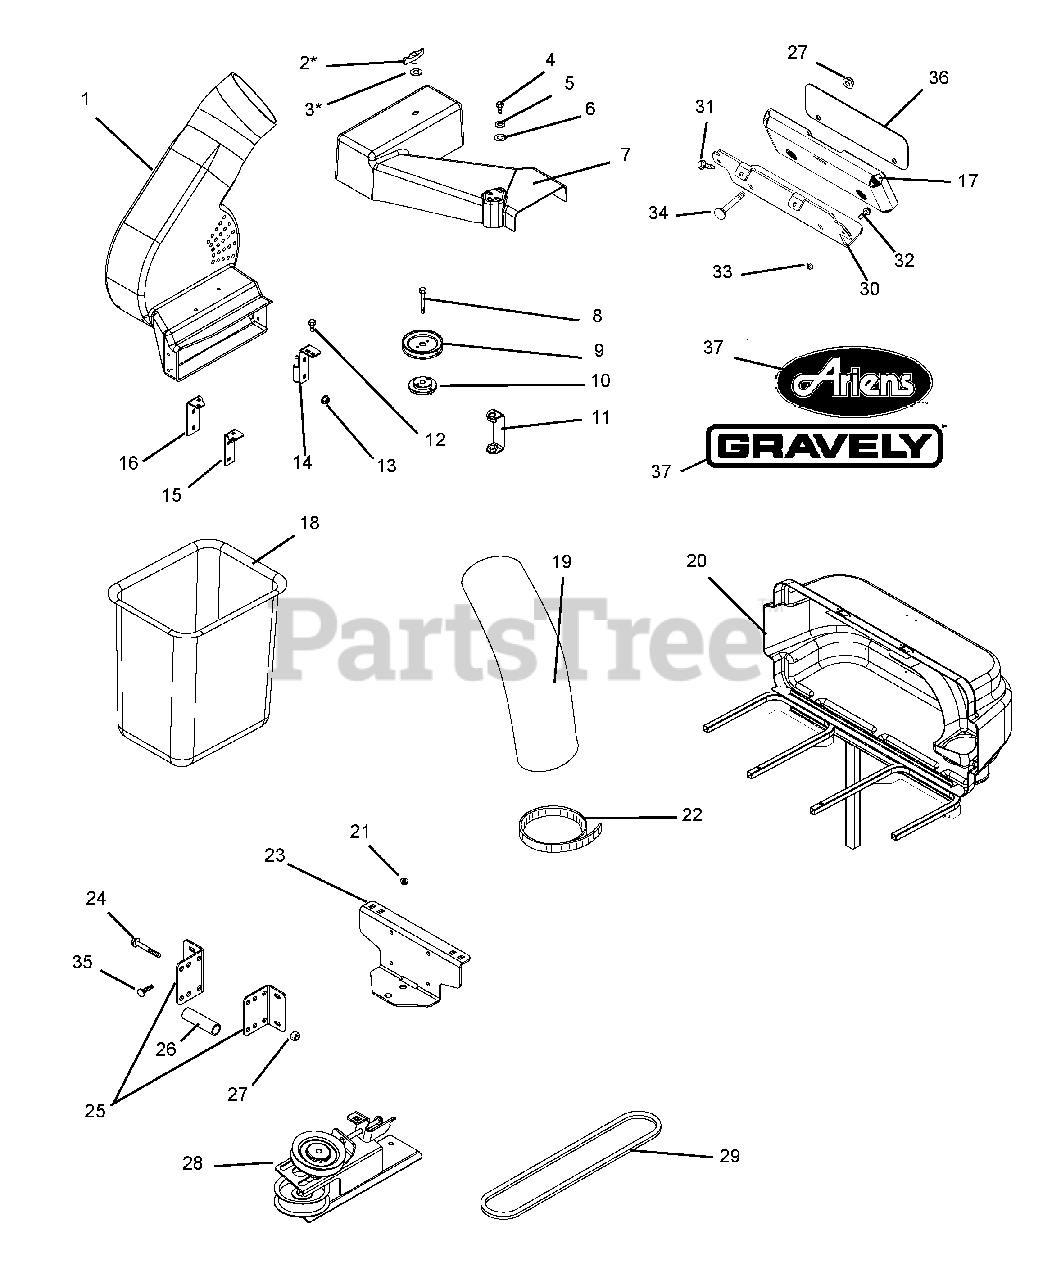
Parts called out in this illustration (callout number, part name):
1	BLOWER (SERVICE ASSEMBLY)
2	KNOB - WING .312-18 UNC
3	WSHR-FL-STL .380X1.50X.062 YWZ
4	@BLT-HEX .38-16X.75 GR5 YWZC
5	@WSHR-LK .38X.094 REG YWZC
6	@WSHR-FL-STL.438X1.00X.083 YWZ
8	BLT-HEX .38-16X1.75 GR8 M-EPYZ
9	SHEAVE, 3.00 DIA.
9	SHEAVE, 4.00 DIA.
10	ASSEMBLY, SHEAVE ADAPTER
11	SPACER, COVER
12	@BLT-HEX .25-20X.75 GR5 YWZC
13	@NUT-LK-TOP-FLG .25-20 YWZC
14	WELDMENT, REAR MOUNT BRACKET
15	BRACKET, FRONT
16	WELDMENT, FRONT MOUNT BRACKET
17	WEIGHT, CAST IRON
18	GRASS BAGGER BASKET
19	HOSE, FLEXIBLE-47"
20	Cover Assembly
21	@NUT-LK-TOP-FLG .38-16 YWZC
22	CLAMP, 7" TOOL-LESS HOSE
23	ASSM, TRAILER HITCH
24	@BLT-HEX .50-13X3.00 GR5 YWZC
25	BKT,BAGGER MOUNT
26	SPACER, PIVOT .500X.750X1.805
27	@NUT-LK-TOP-FLG .50-13 YWZC
28	Idler Assembly
29	V-BELT, HA-WRAPPED
29	V-BELT, HA-RAW EDGE
30	BKRT, CZ WEIGHT
31	@SCR-TAP .38-16X.75 HWH TR YWZ
32	@BLT-HEX .38-16X1.25 GR5 YWZC
33	@NUT-LK-TOP-FLG .38-16 YWZC
34	BLT-RDHDSQNK .50-13X5.00 GR5YZ
35	@BLT-RDHDSQNK .38-16X.75 G5YZ
36	PANEL, DECAL
37	DECAL, ARIENS JEWEL
